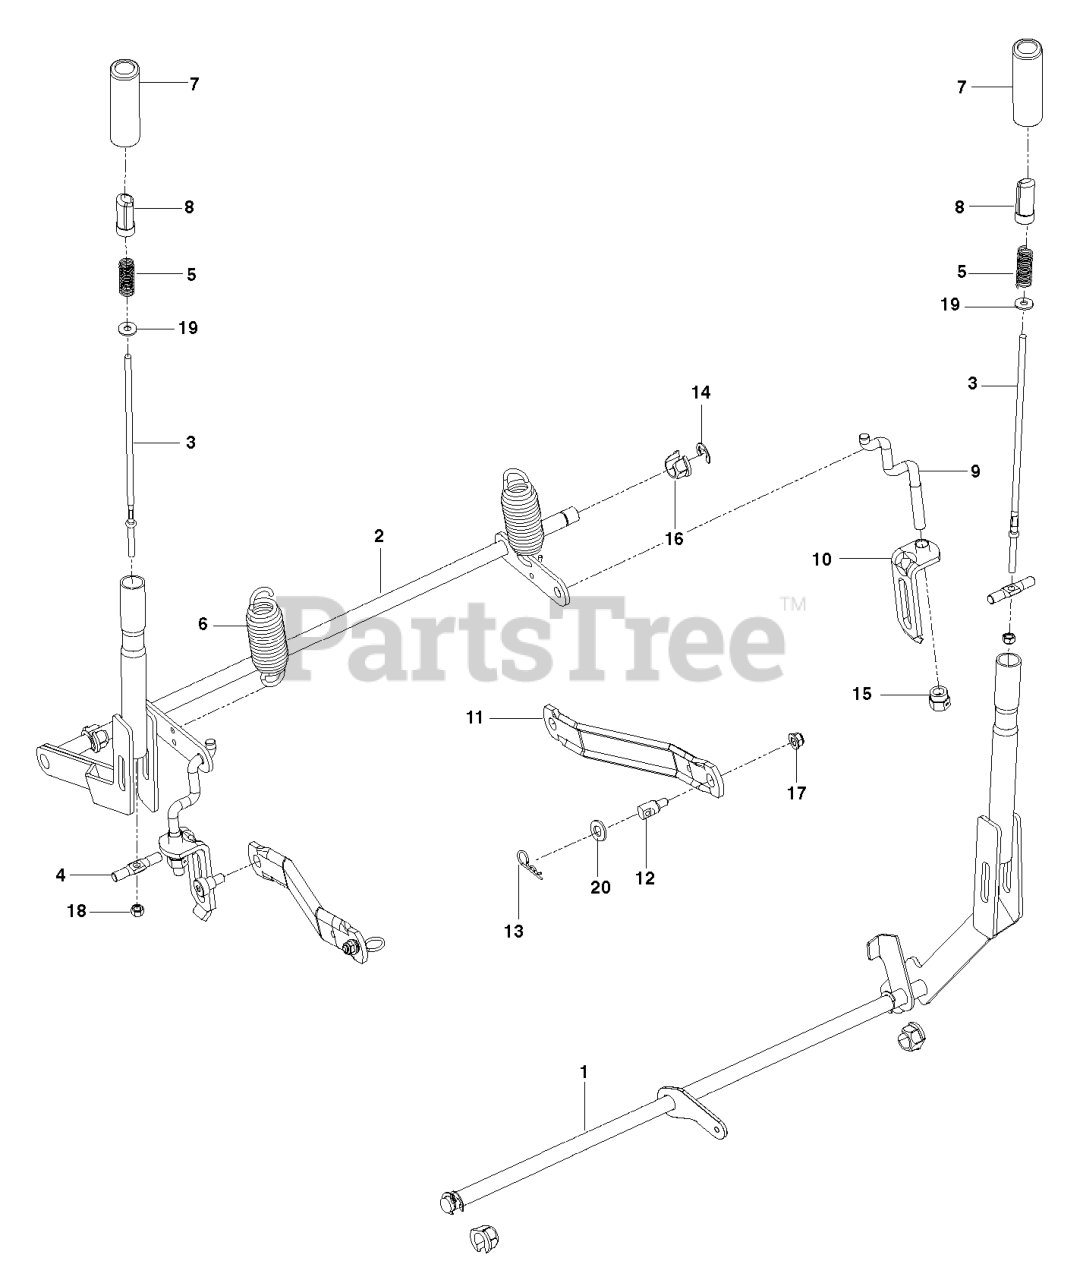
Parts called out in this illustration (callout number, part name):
1	SUBASM.SHAFT.BRAKE.WLDMNT.MED
2	DECK.LIFT.PNT.WELDMENT.RZ.BLK
3	ROD, HANDLE RELEASE
4	ROD LATCH RELEASE
5	SPRING, COMPRESSION
6	SPRING
7	GRIP, HANDLE, BLACK 4"
8	BUTTON, PUSH, BLACK
9	LINK, REAR SUSPENSION
10	ASSEMBLY, BRKT LINK
11	ARM.SUSPENSION.MOWER
12	STUD.FASTNER.W/ANTI-ROTATE
13	HAIRPIN #4
14	E-RING 5/8
15	NUT, LIFT LINK 7/16-20
16	PLASTIC NUT
17	5/16-18 NYLOC FLANGE NUT
18	NUT.1/4-20.HEX.NYLOC.ZD
20	WASHER 5/8 FLAT
